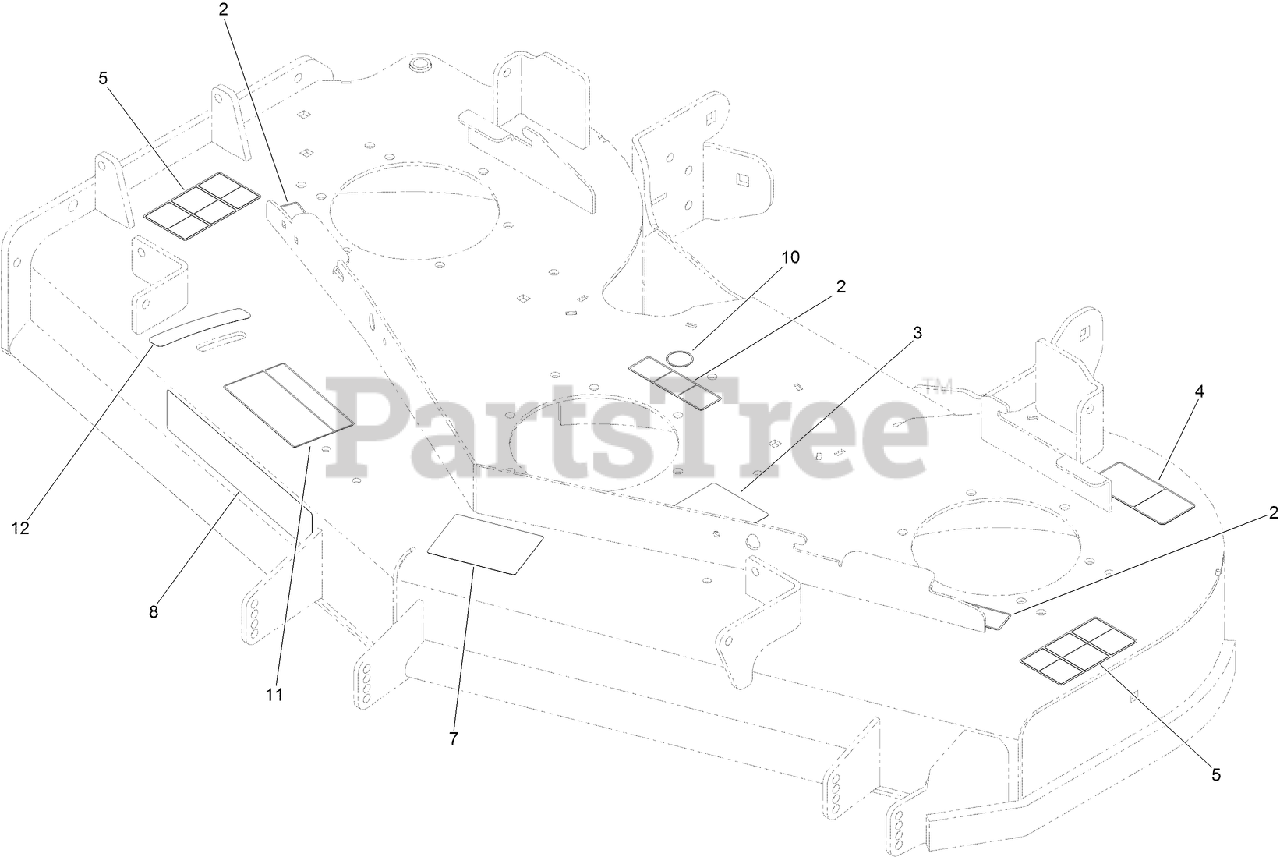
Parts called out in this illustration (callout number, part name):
2	DECAL-MISSING, COVER
3	DECAL-ROUTING, DECK BELT
4	DECAL-TORQUE, BLADE BOLT
5	DECAL-DANGER
7	DECAL-SCALP, ANTI
10	DECAL-GREASE
11	DECAL-ADJUSTMENT, BAFFLE
12	DECAL-SETTING, BAFFLE
